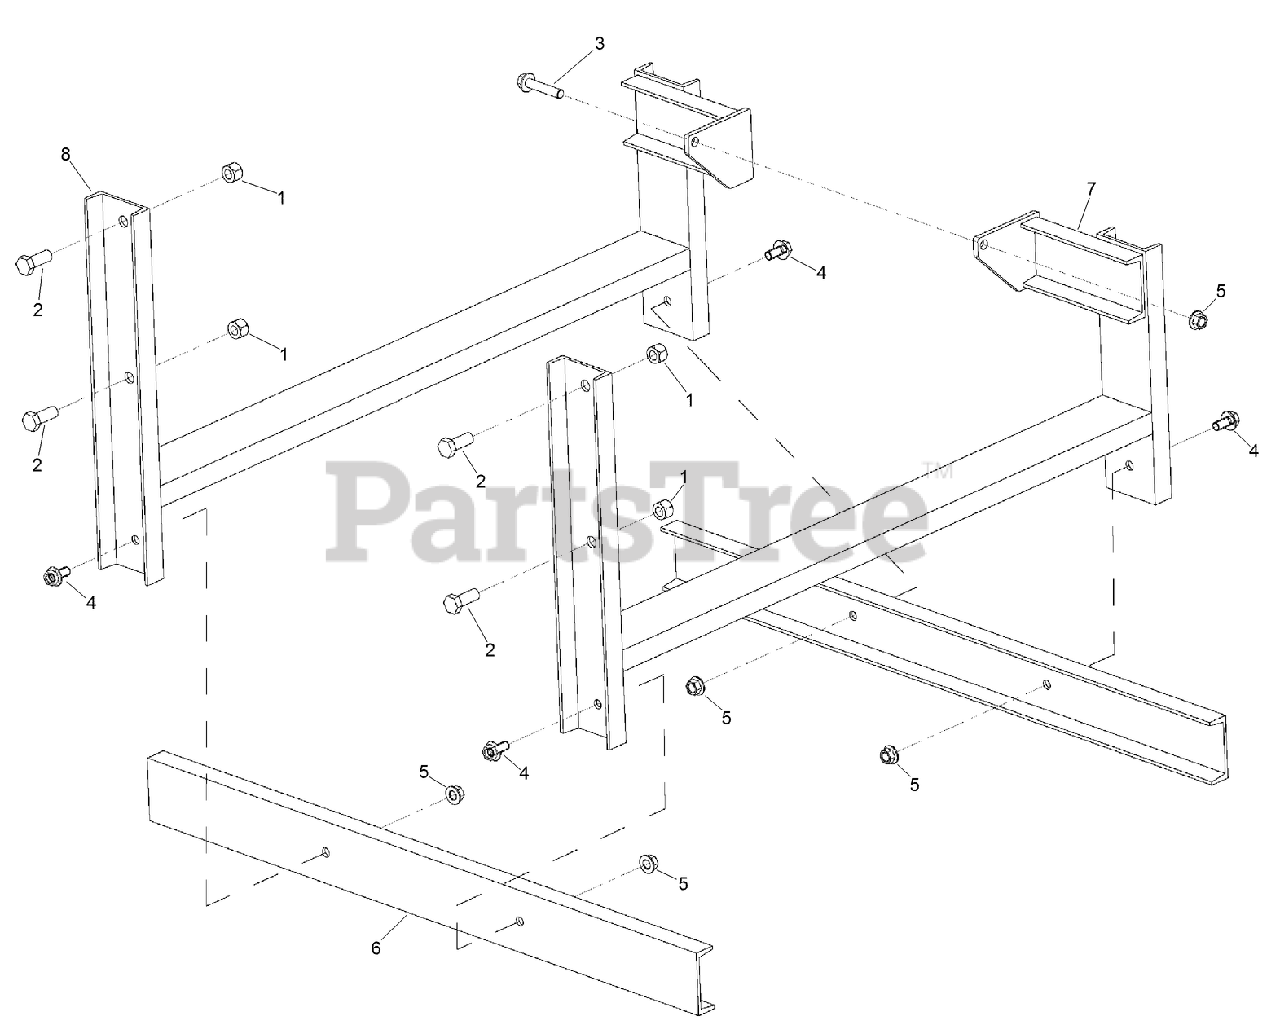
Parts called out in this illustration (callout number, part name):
3	SCREW, METRIC FLANGE w/BODY - M20 x 100
4	SCREW, METRIC FLANGE FULL - M20 x 40
5	NUT, METRIC HEX FLANGE - M20, Zinc
6	CHANNEL
7	ROCK SAW STAND - RH
8	ROCK SAW STAND - LH
